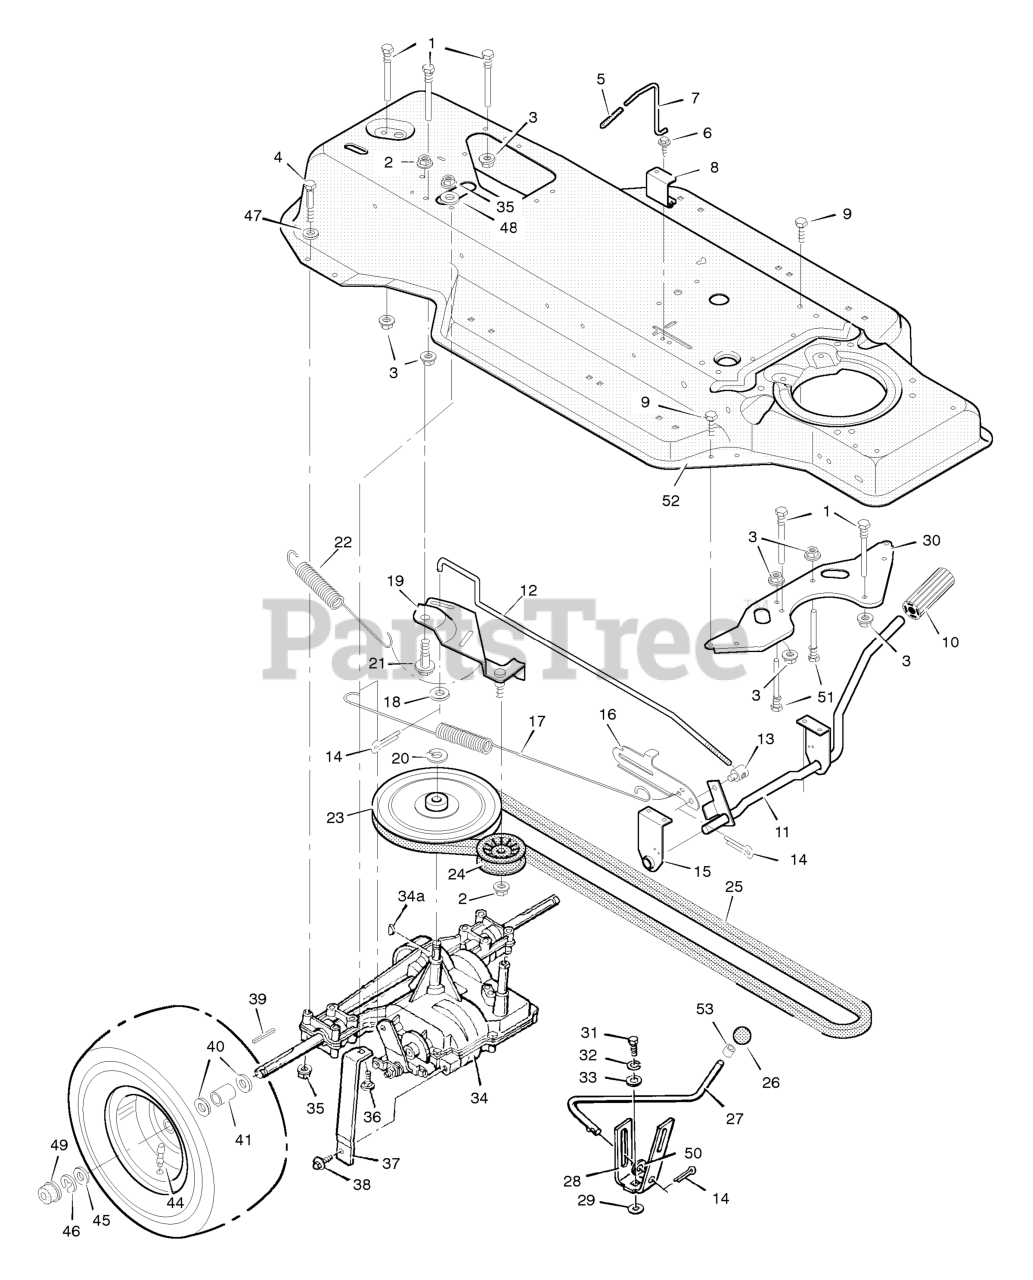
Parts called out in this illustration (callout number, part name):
1	Guide, Belt
2	Locknut, Flange
3	Nut, Flange
4	Bolt, Hex
7	Rod, Control
8	Guide, Bracket
10	Clutch and Brake Pedal
11	Lever Assembly
12	Rod, Clutch
13	Nut, Adjustable
14	Pin, Cotter
15	Bracket, Support
16	Latch, Park Brake
17	Spring, Brake Extension
18	Washer
19	Bracket Assembly, Idler
20	Ring, Retainer
21	Bolt, Shoulder
22	Spring, Drive Extension
23	Pulley, Motion Drive
24	Pulley, Backside Idler
25	Belt, Motion Drive
26	Knob, Shift Lever
27	Lever, Shift
28	Yoke, Shift
30	Plate, Belt Guide
31	Bolt, Hex
32	Lockwasher
34	Transaxle, Peerless **
34A	Woodruff Key No. 9
35	Nut, Flange
36	Bolt, Carriage
37	Support, Transaxle
39	Key, Square
41	Spacer, Transaxle
43	Wheel & Tire Assembly
44	Stem, Valve
46	E- Ring
47	Washer
49	Hub Cap
50	Washer
51	Guide, Belt
52	Frame Assembly
53	Ring, Tolerance
57	Screw
